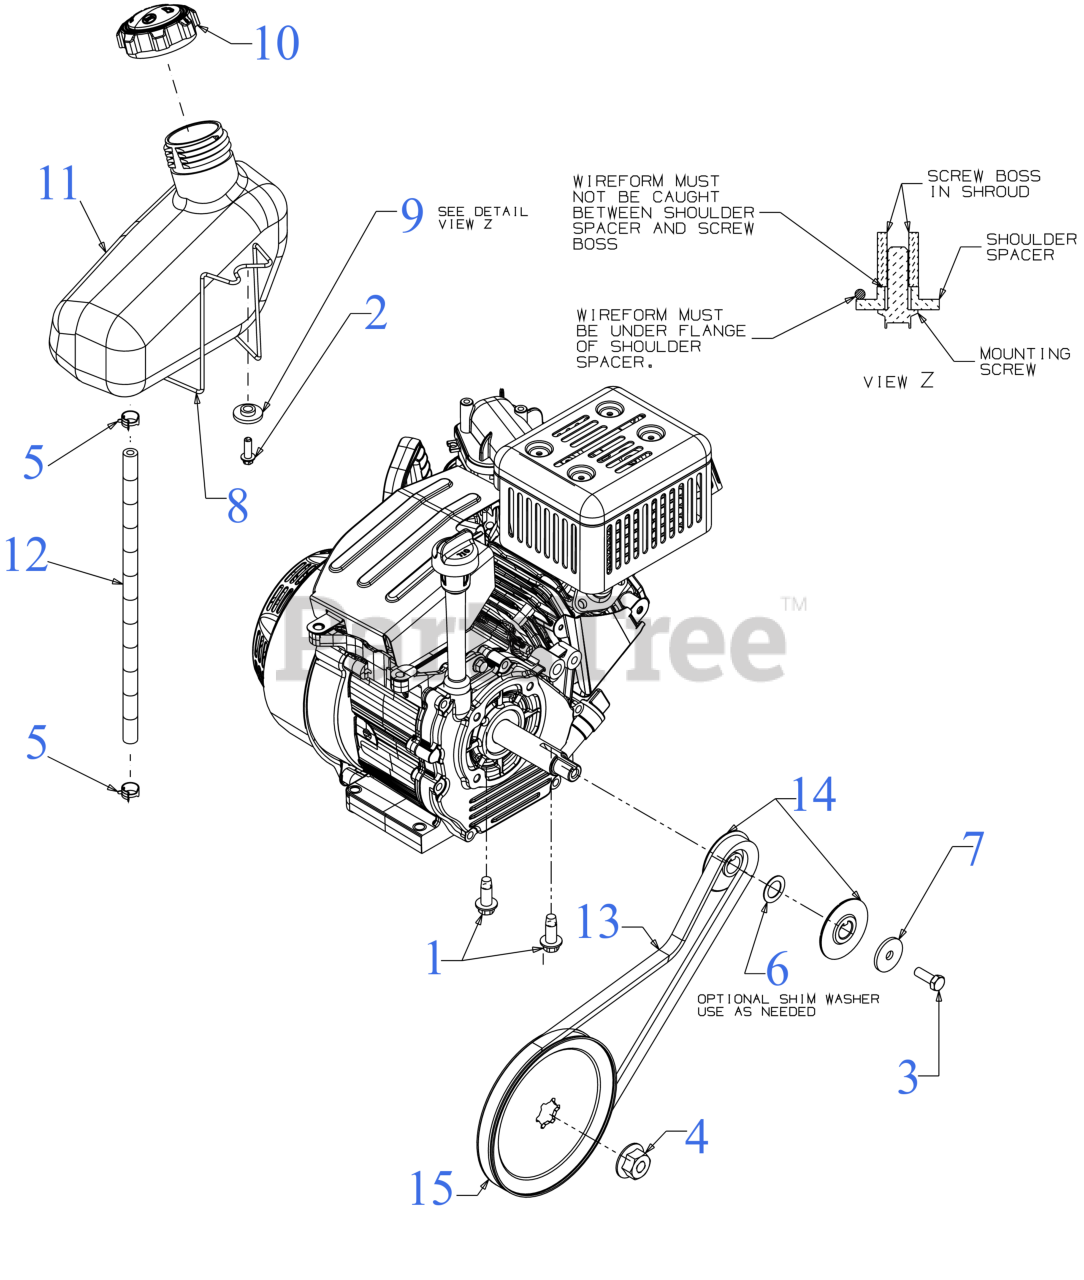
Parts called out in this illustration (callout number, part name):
1	SCREW 3/8-16 x 1
2	SCREW 1/4 x .750
3	SCREW 5/16-24 x .875 GR5
4	FLANGE NUT W/HUB
5	HOSE CLAMP 1/20
6	FLAT WASHER
7	WASHER-5/16 x 1.25X 1.27
8	FUEL TANK WIRE SUPPORT
9	SHOULDER SPACER
10	FUEL CAP
11	FUEL TANK (2 QT)
12	FUEL HOSE 1/4-12"
13	V-BELT .500 x 35.00LG
14	HALF PULLEY
15	AUGER PULLEY
